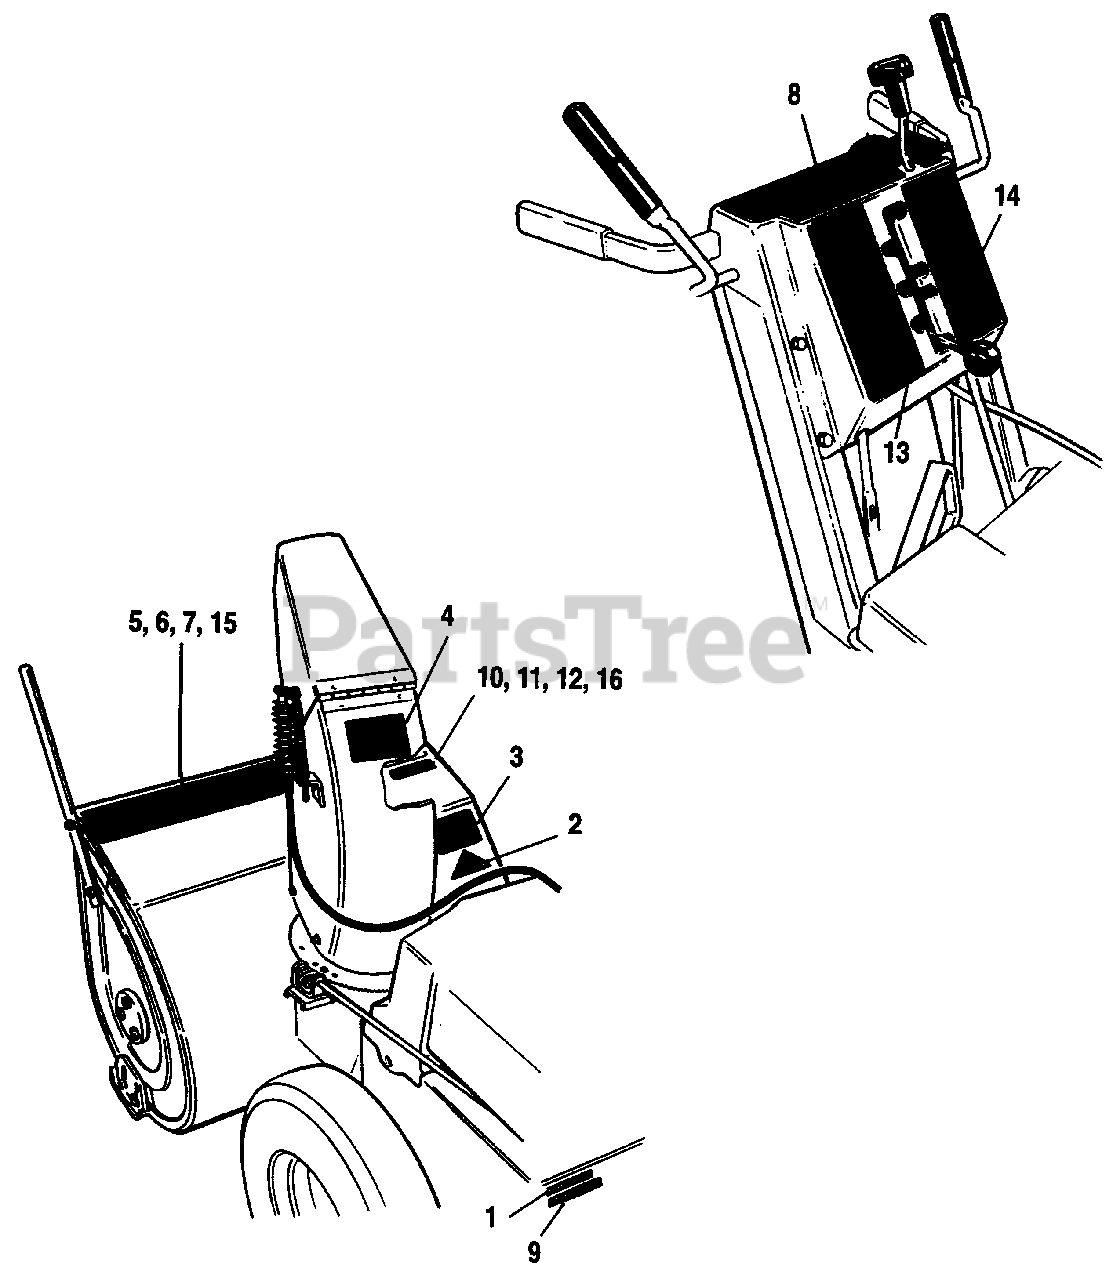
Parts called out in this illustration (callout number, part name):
1	I.D. Tag
2	DECAL, OPEI
3	DECAL, Danger, Auger
4	DECAL, Danger, Blower
5	DECAL, Auger, Simplicity Logo, 8-60
6	DECAL, Auger, Simplicity Logo, 8-70
7	DECAL, Auger, Simplicity Logo, 10-80
8	DECAL, Dash
9	DECAL, Touch Up Paint
10	DECAL, Auger, 10-80
11	DECAL, Auger, 8-70
12	DECAL, Auger, 8-60
13	DECAL, Shift Pattern, RH
14	DECAL, Shift Pattern, LH
15	DECAL, Auger, Simplicity Logo, 9-70
16	DECAL, Auger, 9-70
